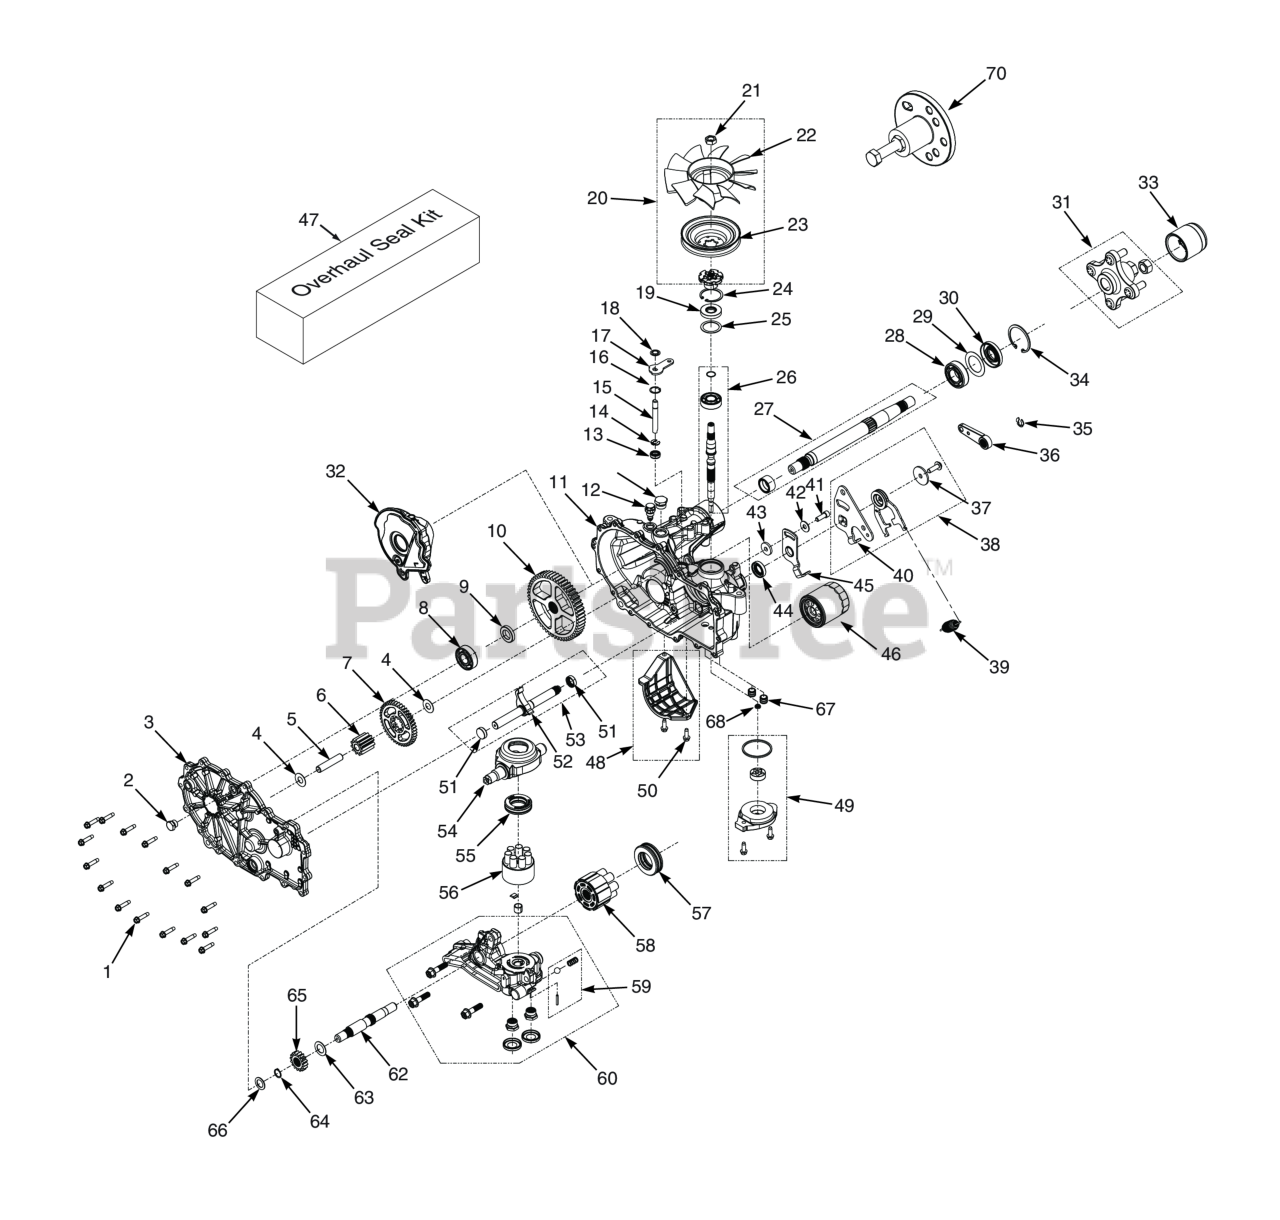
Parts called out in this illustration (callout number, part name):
1	Bolt, Hex Head 1/4-20 x 1-1/8"
2	Plug, External Hex Vent 9/16-18
3	Kit, Side Cover LH
4	Washer, .5 x 1.0 x .03
5	Jackshaft Pin
6	Gear, 11T
7	Gear, 43T
8	Kit, Bearing
9	Spacer, .750 x 1.320 x .257
10	Gear, 54T
11	Kit, Main Housing LH, Charge, Control
12	Fitting, Transmission - SFZ61
13	Seal, Lip .375 x .75 x .25
14	Ring, .Retaining .375 External
15	Rod, By-Pass
16	R i n g , Retaining .750 Internal
17	Arm, By-Pass
18	Ring, Retainging .375 External
19	Seal, Lip 17 x 40 x 7
20	Kit, Fan/Pulley
21	Nut, Hex Locking 1/2-20
23	Pulley
24	R i n g , Retaining 2.06 Internal
25	Washer, 1.23 x 1.56 x .04
26	Kit, Input Shaft
27	Kit, Shaft, Axle
28	Bearing, Ball 1.0 x 52 x 15 Open
29	Spacer, 1.355 x 2.035 x .021
30	Seal, Lip TC4 1.0 x 2.06 x .38
31	Hub Kit
32	Fitting 9 /16 - 18, Breather
33	Cap, Axle
34	R i n g , Retaining 2.06 Internal
35	Ring, Retaining External .375"
36	Handle, Brake
37	Washer, .343 x 1.5 x .062
38	Kit, RTN Assembly
39	Spring, RTN
40	Arm, Control
41	Bolt, Hex Head Cap Screw 5/16-24 x 1" Patch
42	Washer, 7/16 x 7/8 OD x .06 HT
43	Spacer, .32 ID x 1.005 OD x .1495 Thk
44	Seal, Lip 18 x 32 x 7
45	Arm, Neutral
46	Filter, Oil
47	Kit, Seal (ZT-2800)
48	Kit, Filter Guard (LH)
49	Kit, Charge Pump
50	Bolt, 1/4-20 x 3/4"
51	O-Ring, -111 x .103 x 424
52	Pawl, Brake
53	Kit, Outboard, RH Rot B / LH Rot A (LH)
54	Trunnion, Swashplate
55	Ball Thrust Bearing
56	Kit, Cylinder Block
57	Thrust Ball Bearing Assembly
58	Kit, 16cc Cylinder Block Assembly (steam
59	Kit, Charge Relief
60	Kit, Center Section
61	Screw, Hex Flange Head 3/8-16 x 1-1/2"
62	Shaft, Motor
63	Washer, .72 x 1.16 x .04
64	Ring, Retaining .625
65	Gear, 16T
66	Washer, HT .62 ID x 1.0 OD x .05 Thick
67	Tube, Charge Triple O-ring
68	Kit, Gerotor Seal
69	Plug, 3/4-16
70	Kit, Hub Puller
